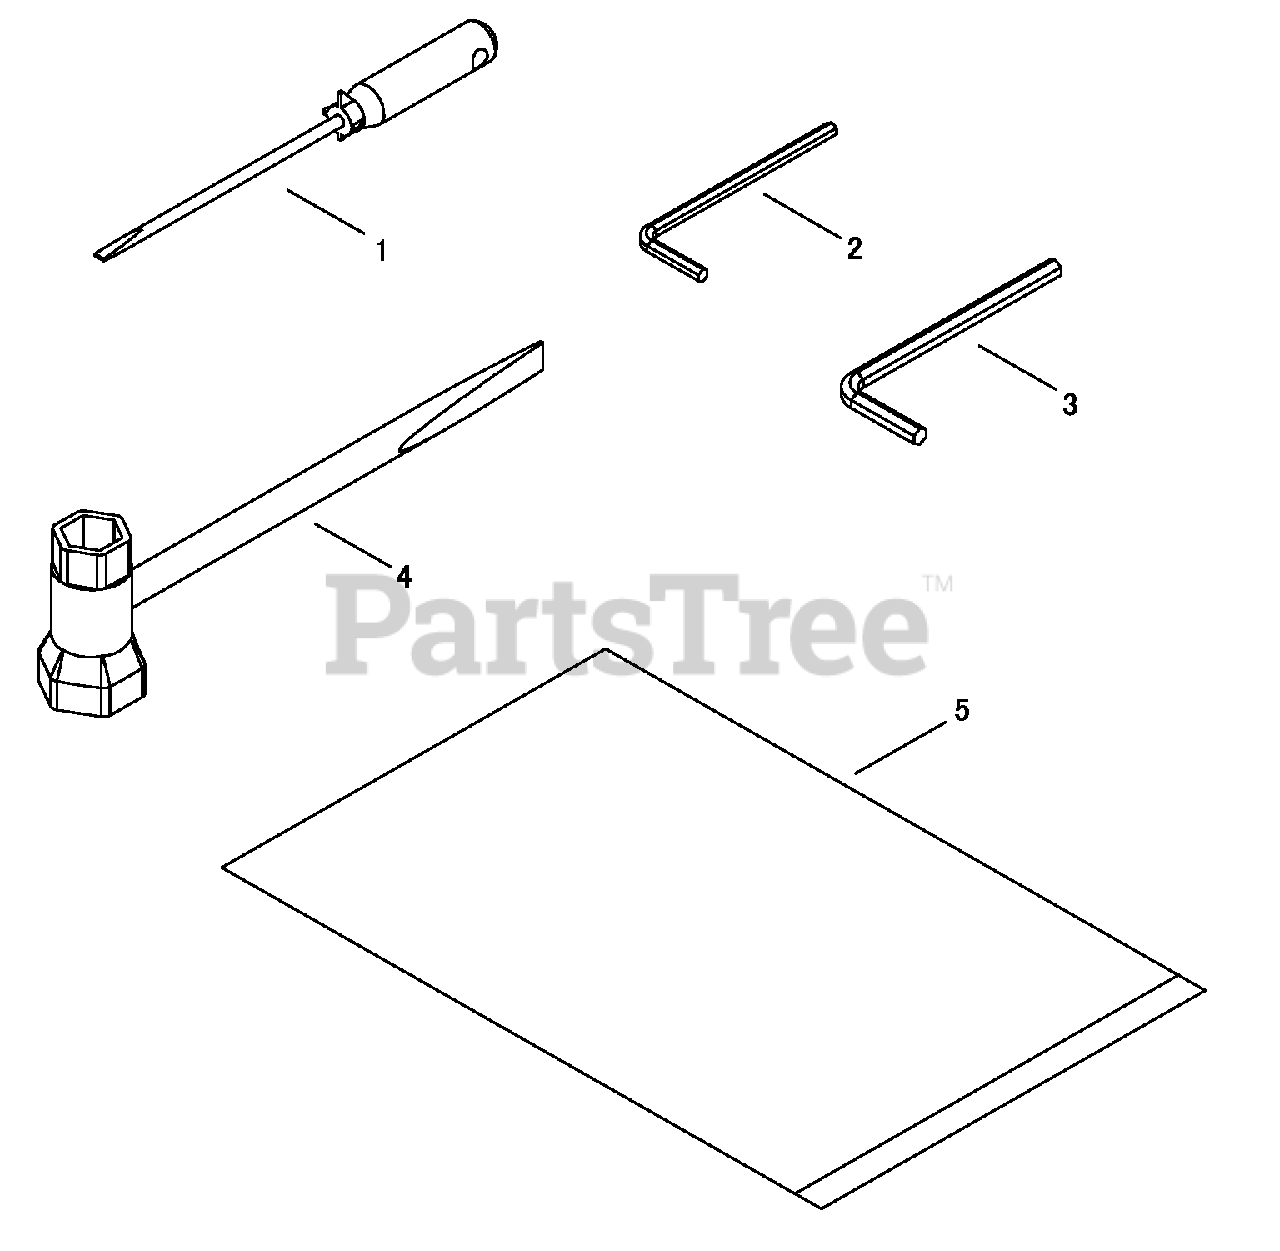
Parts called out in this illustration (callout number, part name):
1	SCREWDRIVER
2	HEX KEY - 3mm
3	HEX KEY - 4mm
4	T-WRENCH - 13X19mm
5	BAG, TOOL
